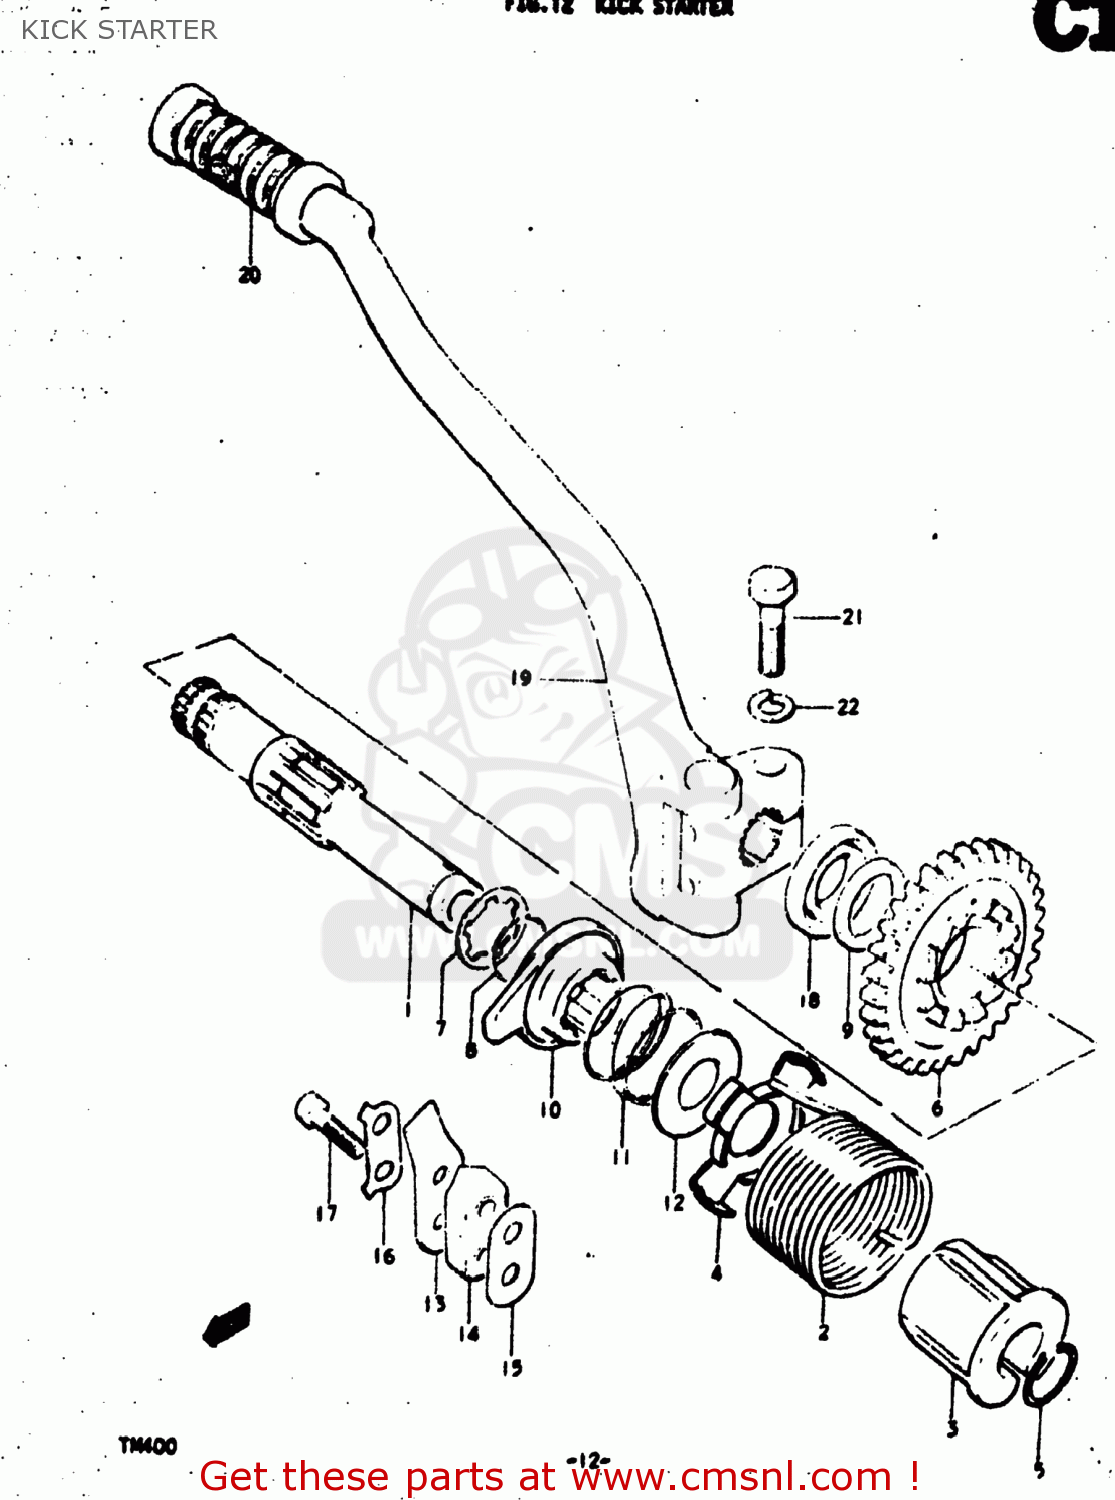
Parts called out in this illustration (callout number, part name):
1	SHAFT,KICK STARTER
2	SPRING
3	GUIDE,KICK SHAFT SPRING
4	HOLDER,KICK SHAFT SPRING
5	CIRCLIP
6	GEAR,KICK STARTER DRIVE
7	WASHER,LOCK
8	CIRCLIP
9	WASHER
10	STARTER,KICK
11	SPRING
12	WASHER
13	GUIDE,KICK STARTER
15	WASHER
16	WASHER
17	BOLT
18	SEAL,OIL(20X37X7)
19	LEVER ASSEMBLY,KICK STARTER
20	RUBBER,KICK STARTER PEDAL
21	BOLT
22	LOCK WASHER
